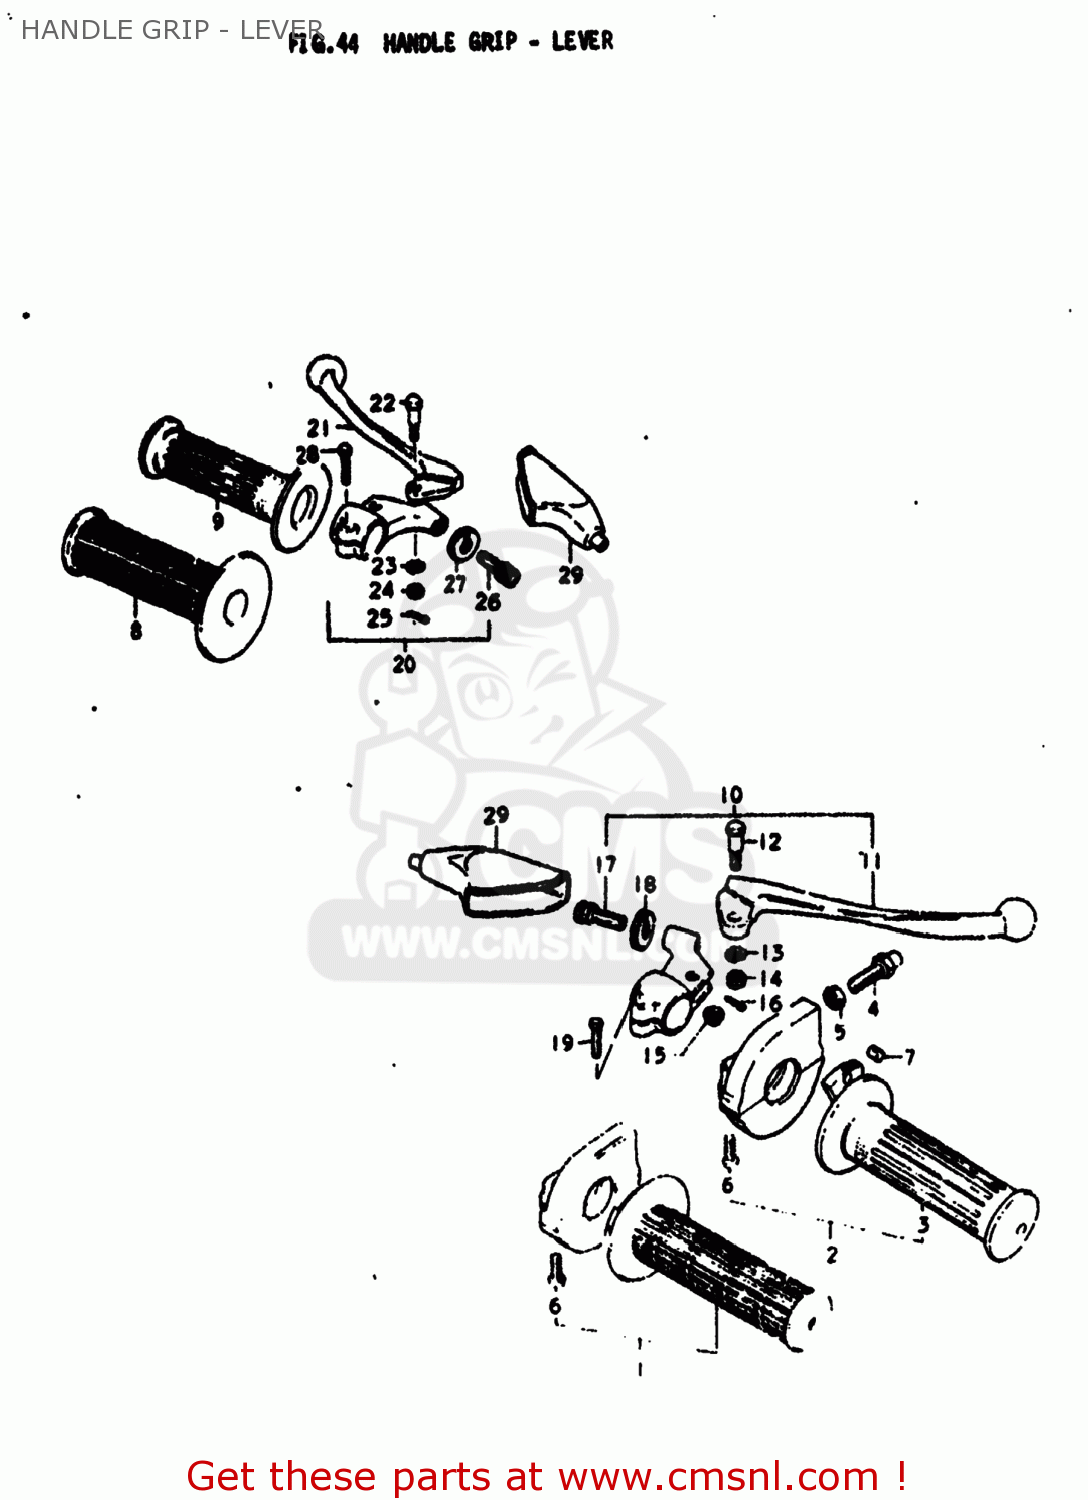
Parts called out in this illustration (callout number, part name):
1	CASE ASSEMBLY,THROTTLE
2	GRIP ASSY,THROTTLE
3	GRIP,THROTTLE
5	NUT
6	SCREW
7	PIECE,THROTTLE END
8	GRIP,LEFT
9	GRIP,LEFT
10	LEVER ASSEMBLY,BRAKE
11	LEVER,BRAKE
12	BOLT,LEVER
13	LOCK WASHER
14	NUT,LEVER FITTNG
15	NUT 6MM
16	COTTER PIN
17	ADJUSTER,CABLE
18	NUT,CABLE ADJUSTER
19	SCREW
20	LEVER ASSEMBLY
21	LEVER,CLUTCH
22	BOLT,LEVER
23	LOCK WASHER
24	NUT,LEVER FITTNG
25	COTTER PIN
26	ADJUSTER,CABLE
27	NUT,CABLE ADJUSTER
28	SCREW
29	COVER,CLUTCH LEVER
